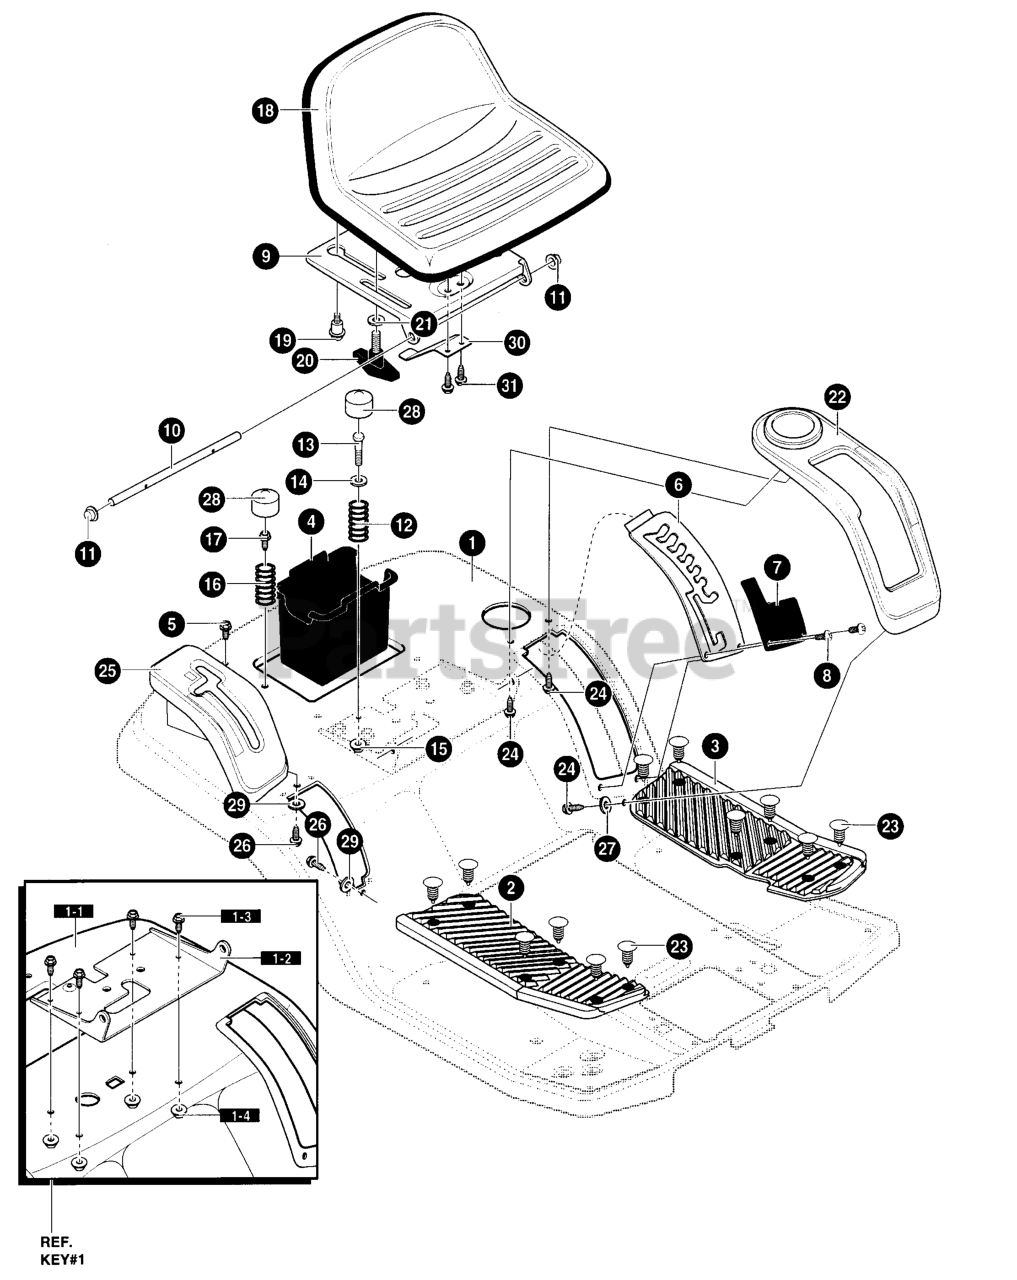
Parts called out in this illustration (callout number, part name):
1	LARGE SEAT DECK
1-1	SEAT DECK, LARGE
1-2	BRACKET, PIVOT SEAT
1-3	SCREW, 5/16-18 x 0.75
1-4	NUT, 5/16-18
2	FOOT REST PAD RH
3	FOOT REST PAD LH
4	CONTAINER, BATTERY
5	SCREW 1/4-20X.63
6	PLATE, LIFT DETENT
7	COVER, LIFT DETENT
9	SUPPORT, SEAT
10	HINGE SEAT PIVOT
11	NUT, PUSH CAP
12	SPRING, COMPRESS
13	BOLT, SHOULDER 1/4-20
14	WASHER CUP
15	NUT, 1/4-20
16	SPRING, COMPRESS
17	SCREW 5/16-18X.75
19	BOLT, SHOULDER 5/16-18
20	BOLT, WING 5/16-18X.50
21	Washer
22	COVER, DETENT PLATE
23	FASTENER, RATCHET
24	SCREW, 1/4-15X.44/.53
25	COVER, HAND/FOOT, HYDRO
26	SCREW, 1/4-15X.44/.53
27	FLATWASHER
28	CAP
29	WASHER, FLAT
30	SPRING, LEAF
31	SCREW, 1/4-20X.50
